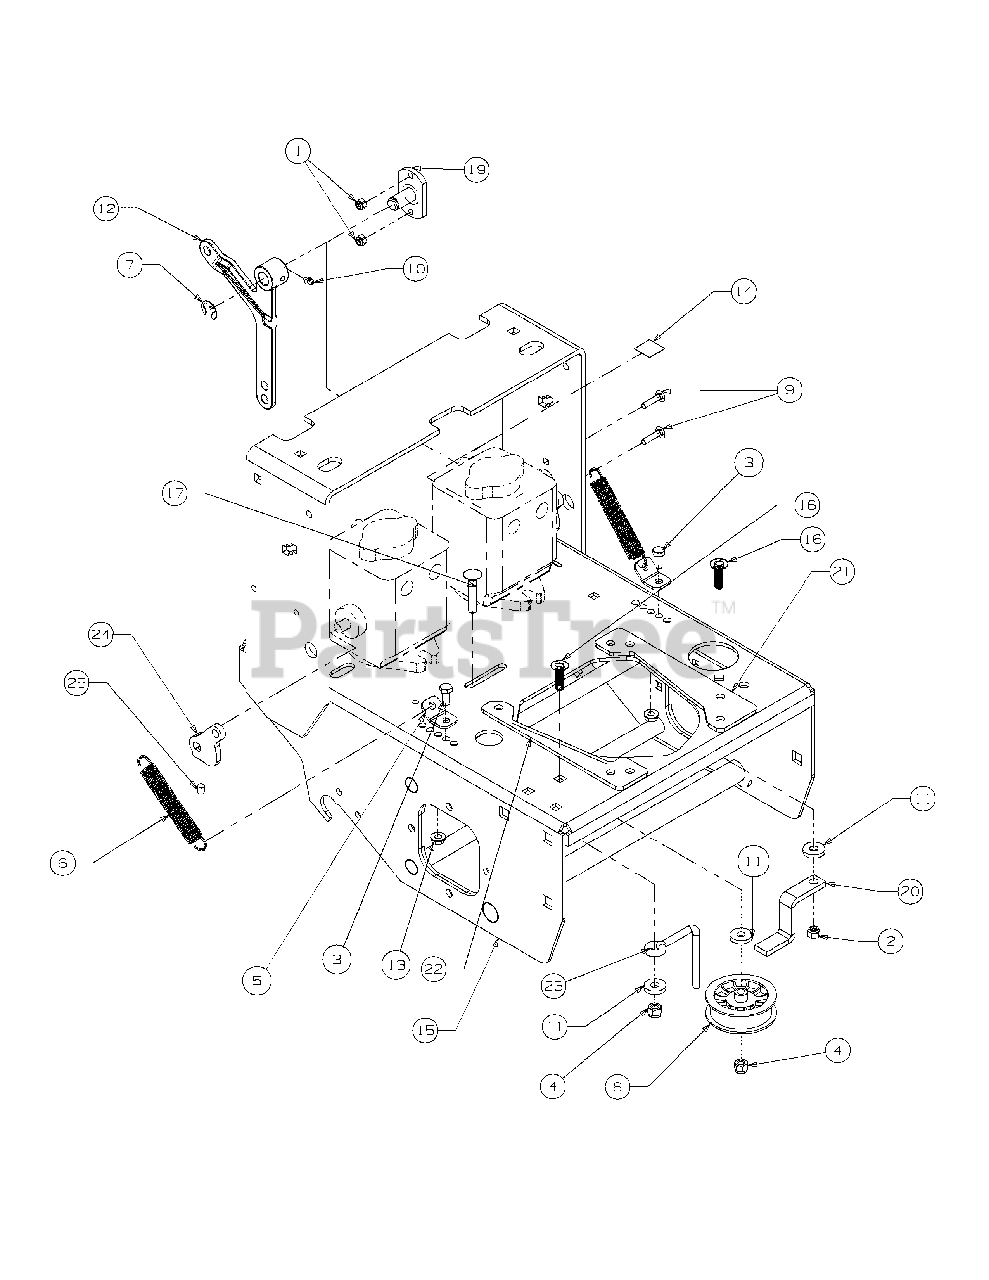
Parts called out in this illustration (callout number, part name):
1	Nut, L, Nylon Insert, 1/4-20 Grade A
2	Nut, 5/16-18, Nylock
3	Hex Cap Screw, 5/16-18 x .75
4	Nut, L, Nylon Insert, 3/8-16 Grade A
5	Mounting Bracket, Spring
6	Spring, Music Wire, LE-093G-9, Plated
7	E-Ring, 5/8" #5113-62
8	Pulley, Flat Idler W/Adaptor
9	Carriage Bolt, 1/4-20 x 1.00
10	Grease Fitting, 1/4-28 x 3/16 STR
11	Washer, Idler
12	Bellcrank Clutch, Casting
13	Lock Nut, 5/16-18, Hex Flange Lock
14	Label, Mower, Warn, Open Belt Drive
15	Engine Base Assembly, Hydro
16	Carriage Bolt, 3/8-16 x 1.25 Grade 5
17	Carriage Bolt, 3/8-16 x 2 Grade 5
19	Bellcrank Pivot Weldment
20	Belt Guide, Engine, 36/42/48
21	Spacer, Engine, Left Hand
22	Spacer, Engine, Right Hand
23	Belt Guide, 3.375
24	Pump Lever
25	Set Screw, 5/16-24 x 1.25
